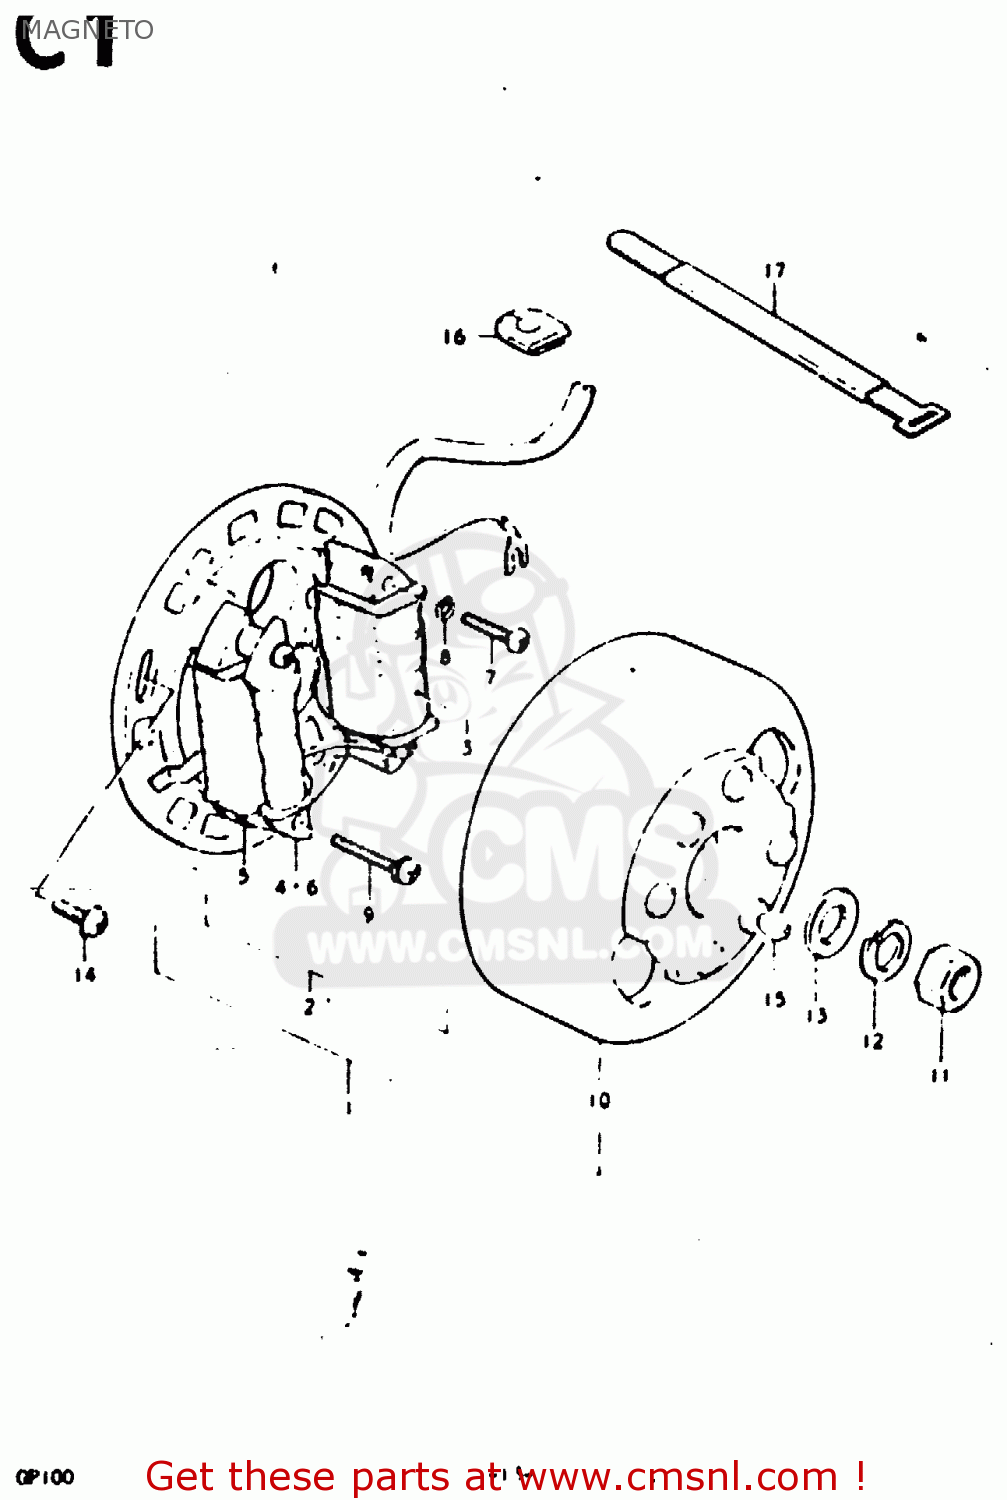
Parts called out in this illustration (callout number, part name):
1	MAGNETO ASSY
2	STATOR ASSY
3	COIL,LIGHTING
4	COIL, IGNITION
7	SCREW 4X25
8	LOCK WASHER
9	SCREW
10	ROTOR
11	NUT (10MM)
12	LOCK WASHER
13	WASHER
14	SCREW(5X14)
15	KEY
16	GROMMET
17	CLAMP
